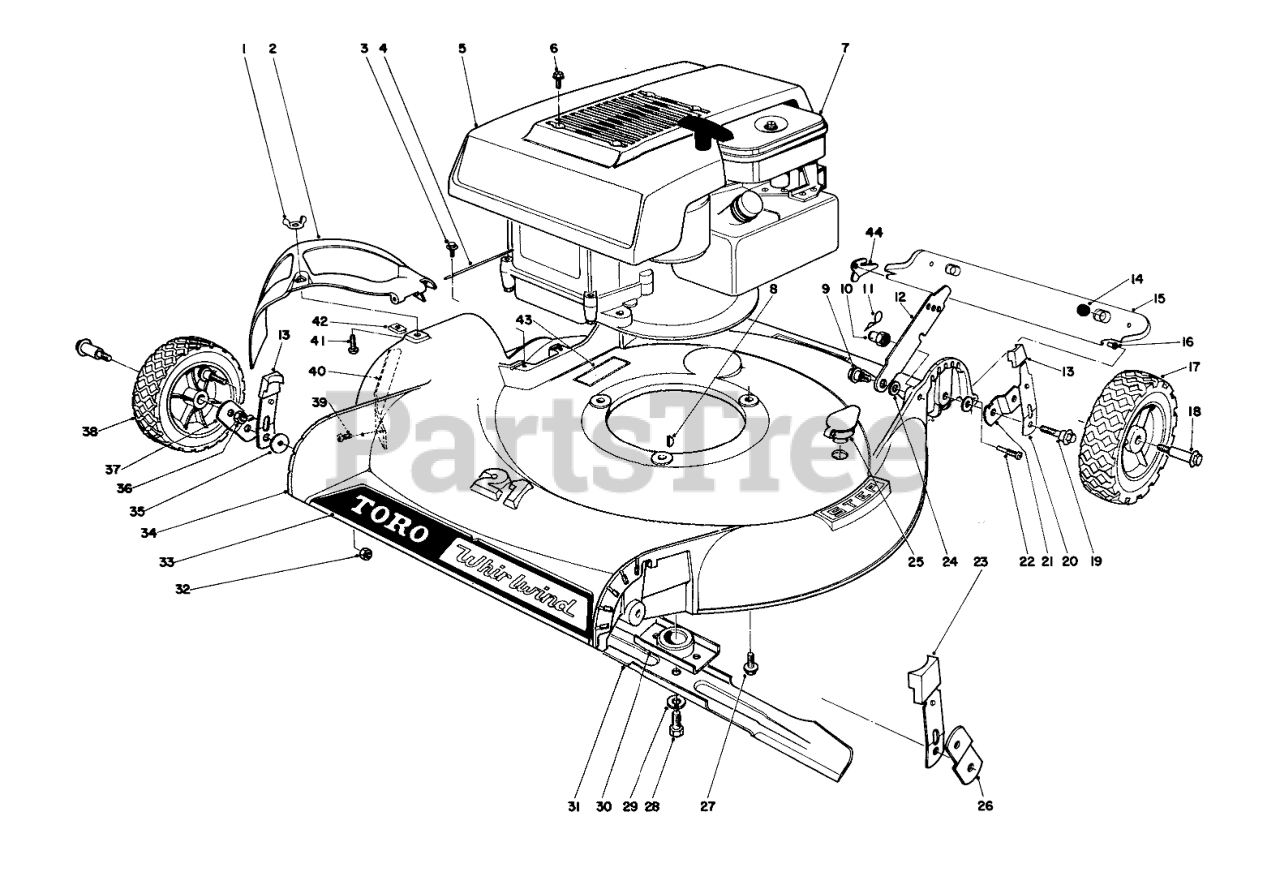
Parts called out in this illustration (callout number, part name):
1	NUT-WING SPECL
2	Deflector
3	SCREW
4	HINGE PIN
5	Shroud
6	8X1/2 SELF TAP SCREW
7	Engine
8	KEY-WOODRUFF
9	SCREW-SHOULDER
10	HANDLE PIVOT NUT
11	PIN-COTTER, HAIR
12	Latch
13	Arm Knob
14	SKID BUTTON
15	Safety Shield (Incl. Ref. 15 & 16)
16	SAFTEY SHIELD BUSHING
17	WHEEL ASM 8
19	PIVOT SCREW
20	Spring Arm
21	PIVOT ARM PLATED
22	SAFTEY SHIELD SCREW
23	Arm Knob
24	SPACER
25	WASHOUT PLUG
26	Pivot Arm
27	SCREW-HWHTF
28	SPECIAL SCREW
29	WASHER-LOCK
30	BLADE RETAINER WA
31	Blade
32	Nut
33	Decal
34	Housing
35	WASHER-PIVOT
36	Nut
37	PIVOT ARM D PLTD
38	WHEEL ASM 7
40	Bar Safety
42	NUT-SPEED
43	Decal
44	Restraint R.H.
